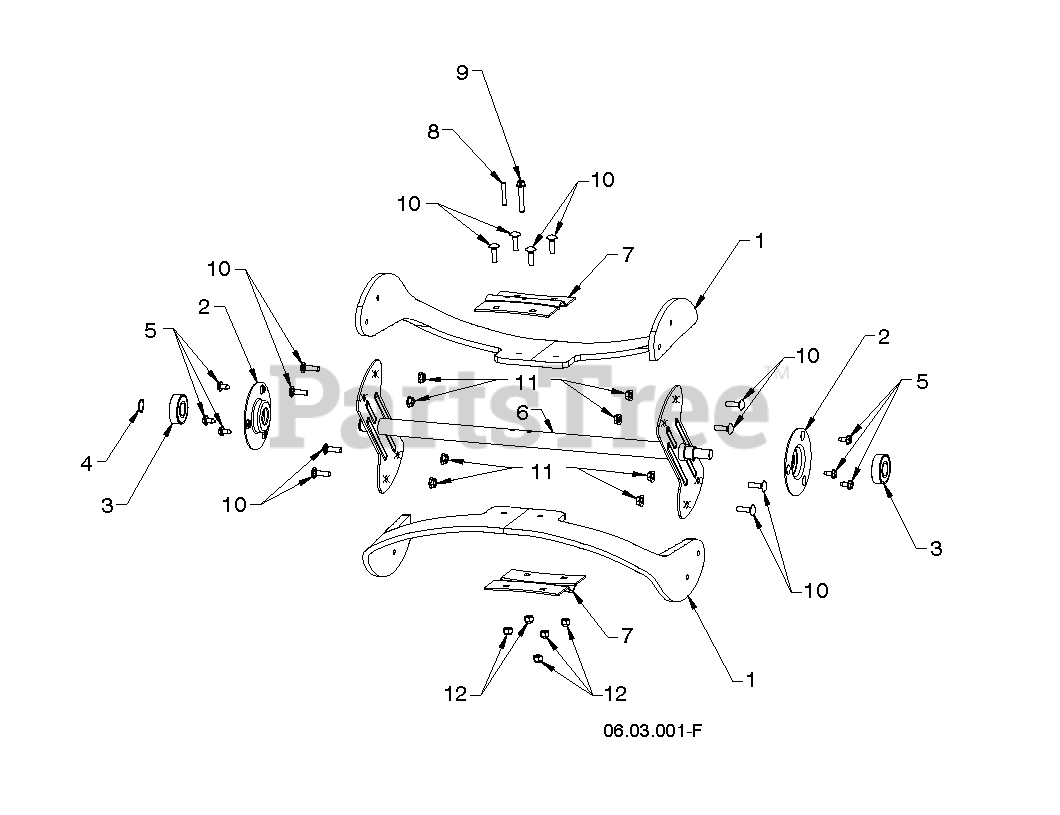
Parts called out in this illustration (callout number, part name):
1	AUGER.BLADE.SS.SNOW
2	SUPPORT.BEARING.SINGLE.STAGE.B
3	BEARING.BALL.MANDREL
4	Ring Retainer # 5100-62 (AYP part number)
5	Screw, Hex Head, Thread Cutting 1/4-20 x 1/2 (AYP part number)
6	WELDMENT.AUGER.SINGLE.STAGE.BL
7	PLATE.CENTER.BLADE.BLACK
8	PIN.ROLL.3/16 X 1-1/4
10	BOLT.CARRIAGE.1/4-20 X 7/8
11	NUT.HEX.FLANGE.1/4
12	NUT
